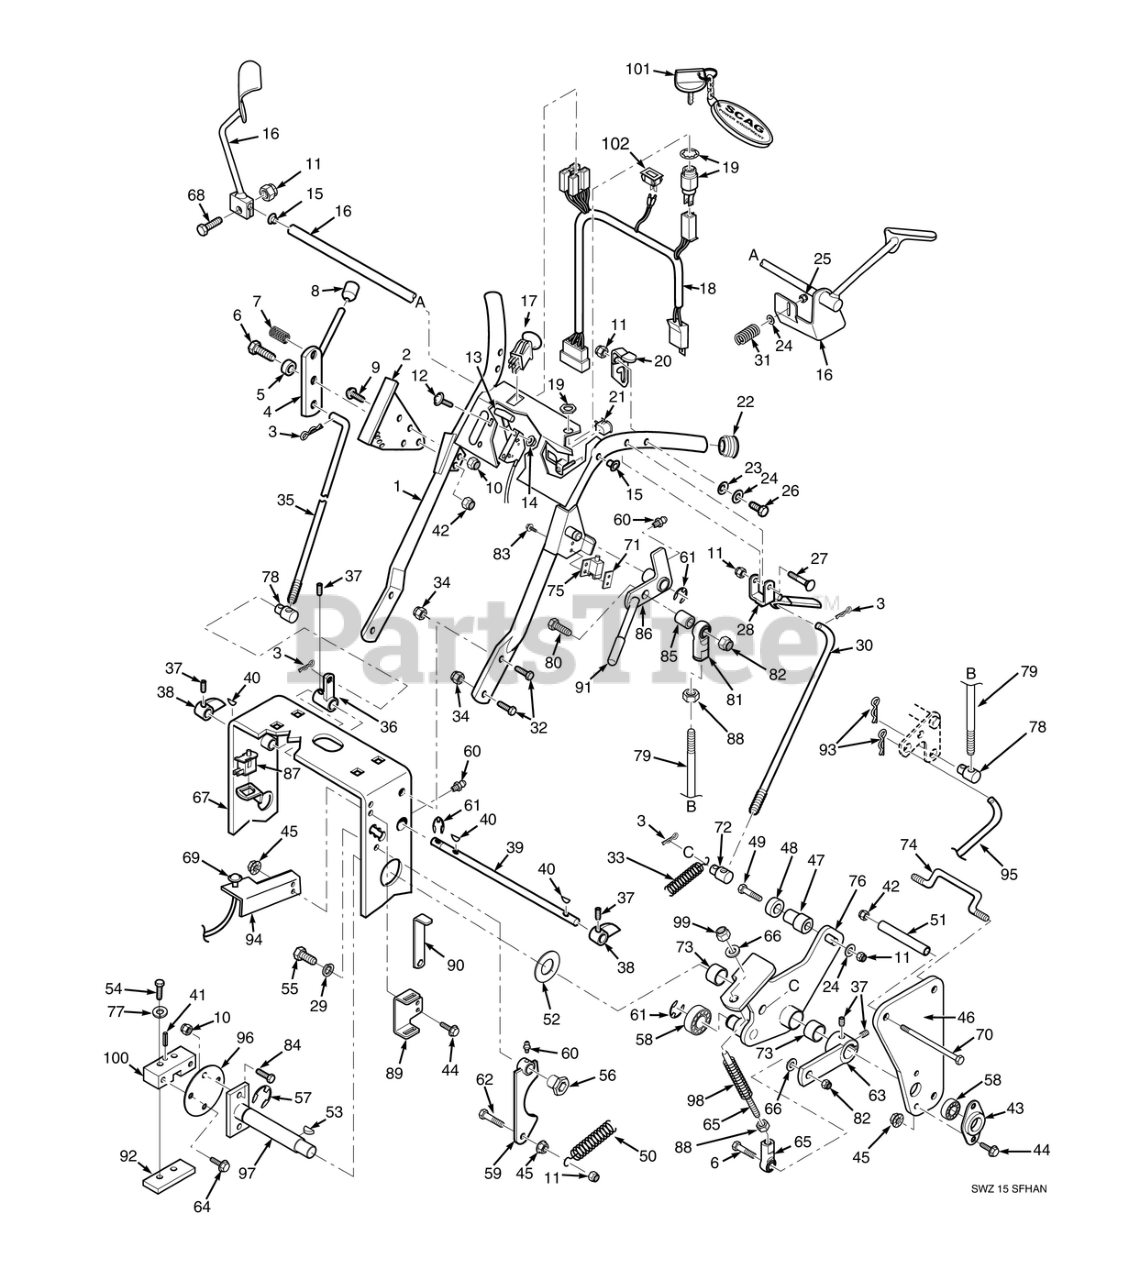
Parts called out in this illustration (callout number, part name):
1	Upper Handle Wlmt. W/Decals
2	QUADRANT, SPEED CONTROL
3	HAIR PIN, .08 DIAMETER X 1-3/16"
4	LEVER, SPEED ADJUSTMENT
5	BUSHING, SPEED ADJUSTMENT LEVER
6	Bolt, Hex Head, 3/8-16 x 1-1/2"
7	BALL PLUNGER
8	KNOB, SPEED ADJUSTMENT LEVER
9	CAPSCREW, 1/4-20 X .75 FLAT HD. HEX SOCKET
10	HEX, NUT, ELASTIC STOP LOCK, 1/4-20
11	HEX NUT, ELASTIC STOP LOCK, 5/16-18
12	Bolt, Carriage #10-24 x 1/2"
13	Throttle Control (15KA & 17KA)
14	Nut, Elastic Stop #10-24
15	Bushing
16	Operator Presence Lever, RH
16	Operator Presence Lever, LH
17	Switch, PTO - 10 Amp
18	Wire Harness, Manual Start
19	KEY SWITCH, MANUAL SRT.(INCL. HWD)
20	Neutral Latch-RH 461241 Neutral Latch-LH
20	Neutral Latch Assembly, LH
21	SWITCH, NEUTRAL INTERLOCK
22	Plug, Handle Bar
23	Socket Head Capscrew #8-32 x 1/2"
24	Flatwasher, 5/16-.375 x .875 x .083 (35BV & 37BV-EFI)
25	HEX NUT, ELASTIC STOP LOCK, 5/16-18
26	Bolt, Hex Head 5/16-18 x 2-1/2" (x3) (35BV & 37BV-EFI)
27	Bolt, Hex Head 5/16-18 x 2-1/2" (35BV & 37BV-EFI)
28	Lever, Steering Control
29	Lockwasher, 3/8" Spring, Kawasaki FX / FS
30	Rod, Steering Control
31	Spring, Operator Presence
32	Capscrew, 3/8-16 x 1.0" Serrated Flange Hex Hd
33	Spring
34	NUT, 3/8-16 SERRATED FLANGE HEX HEAD
35	Rod Speed Control
36	SPEED CONTROL ARM
37	SETSCREW, 1/4-28 X 1/4 H. SOCK., KNURLED CUP
38	CAM, SPEED CONTROL(INCLUDES SETSCREW)
39	JACKSHAFT, SPEED CONTROL(FOR 16" DECK)
40	KEY, 1/8 X 1/2, WOODRUFF # 3
41	Roll Pin, Spring 3/16 x 3/4"
42	HEX NUT, ELASTIC STOP LOCK, 5/16-18
43	FLANGE, JACKSHAFT BEARING
44	Cpscrw, 5/16-18 x 1"Serrated Flange Hex Head
45	Nut, Serrated Flange 5/16-18 (Right Front Engine Mounting, Briggs and Kohler Only)
46	Plate, Side
47	Support, Neutral Support
48	BEARING, SPEED CONTROL BELLCRANK
49	BOLT, HEX HD., 5/16-18 X 1-3/4 FULL THREAD
50	SPRING, IDLER TENSION
51	Spacer, Side Plate
52	Flatwasher, 3/4 (.766 x 1.250 x .060)
53	KEY, WOODRUFF #9, 3/16 X 3/4"
54	SERR. FLG. HEX HEAD CAPSCREW, 5/16-18 X 3/4
55	Bolt, Hex Head, 3/8-16 x 1 Gr. 5
56	B ushing, Brake
57	RETAINING RING, 3/4" EXTERNAL "E"
58	BEARINGS, BALL, NEUTRAL RETURN
59	Cam, Neutral (incl. grease ftng.)
60	Greese Fitting, Straight 1/4 - 28
61	RETAINING RING, 5/8" EXTERNAL "E"
62	Bolt, Heax Head 5/16-18 x 1" (48V / 52V)
63	Lever, Speed Control
64	Bolt, Serrated Flange Hex Head 1/4 x 20 x 3/4"
65	Linkage Assembly
66	Flatwasher, 3/8" Special (.391 x .938 x .105)
67	Engine Deck (16" Wide) with Decals - Small Frame
68	Bolt, 5/16 - 18 x 1 - 1/4" Hex Head
69	Choke Control
70	Bolt, Hex Head 3/8-16 x 4-1/4"
71	Plate, Threaded
72	Swivel Joint, Steering Rod
73	Bushing, oil lube - 3/4 ID x 1.0
74	Rod, Offset
75	Switch, Interlock (see below)
76	Control, LH (inc. bush. & decal)
76	Control, RH (inc. bush. & decal)
77	Lockwasher, 1/4� Spring
78	SWIVEL JOINT, SPEED CONTROL ROD
79	Rod, Brake Lever
80	Capscrew, Hex Head 3/8-16 x 2.0"
81	Rod End, 3/8-24 RH Thread Female
82	HEX NUT, ELASTIC STOP LOCK, 3/8-16
83	Screw, Hex-Slotted Washer Head #10 32 x 3/4"
84	BOLT, HEX HEAD, 1/4-20 X 3/4 GR.5
85	Spacer, Idler
86	Parking Brake Lever w/Grip & Grease Fitting
87	SWITCH, NEUTRAL INTERLOCK
88	HEX NUT, 3/8-24 R.H. THREAD
89	Mounting Bracket, Wrench
90	Wrench
91	GRIP, PARKING BRAKE
92	CLAMP PLATE, PUMP CONTROL
93	COTTER PIN, HAIR - 0.94 X 1.62
94	Bracket, Choke Mounting
95	Rod, Brake Lower
96	Plate, Coupler
97	Shaft, Pump Control
98	Spring, Tracking Adjustment
99	HEX NUT, ELASTIC STOP LOCK, 3/8-16
100	BLOCK, PUMP CONTROL
101	Key, Assembly w/Fob
101	Key w/Shroud Only
102	Hour Meter, Inductive
